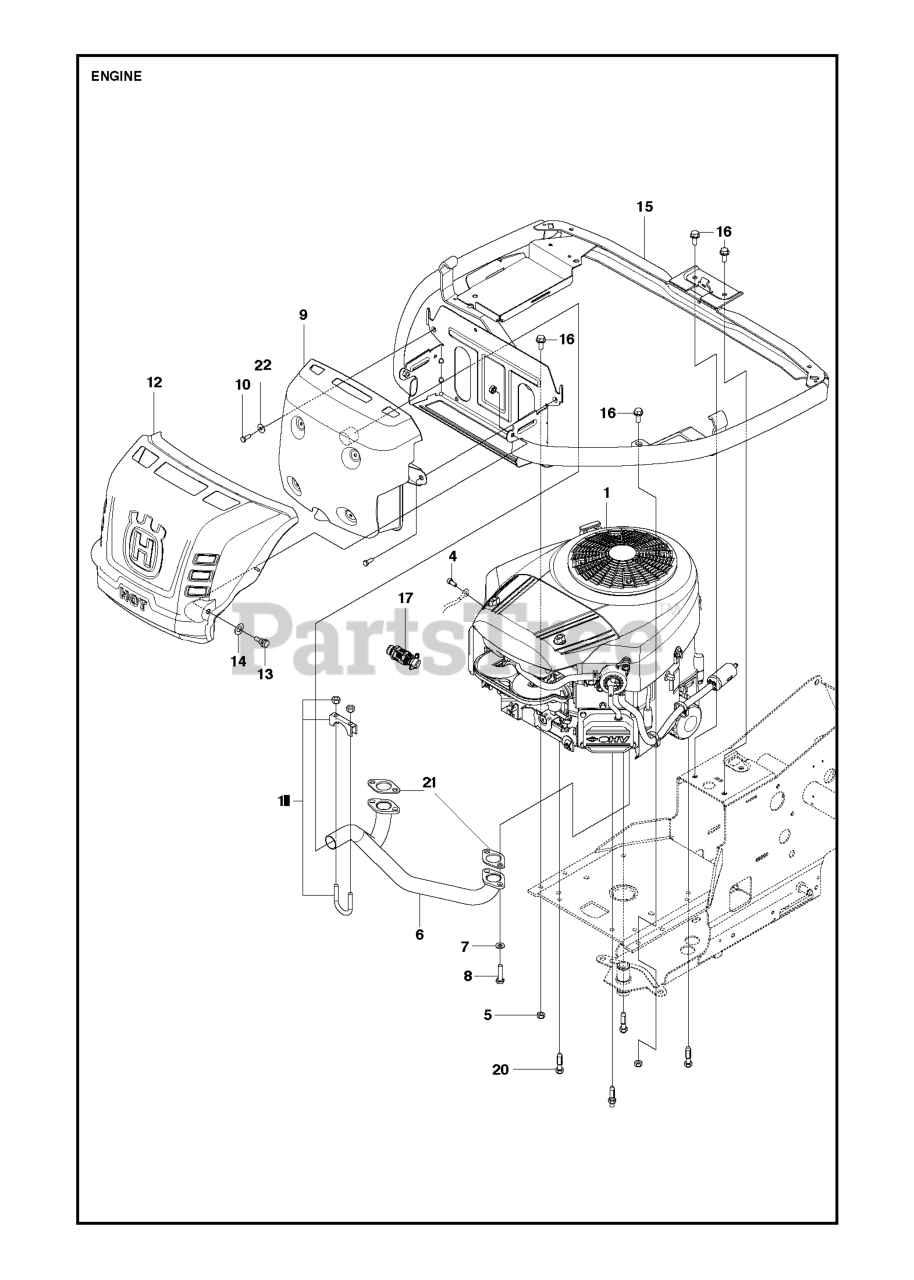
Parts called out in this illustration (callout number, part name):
1	ENGINE
5	LOCKNUT M8
6	MANIFOLD
6	Mainfolds
7	WASHER BRB 8.4X17
8	BOLT
8	SCREW
9	MUFFLER
11	CLAMP ASSY EXHAUST
12	HEAT SHIELD
14	SPRINGWASHER
15	ENGINE FRAME
17	VALUE.OIL.DRAIN
20	STUD SCREW
21	FLANGE
22	WASHER - 26X6.5X1.6
